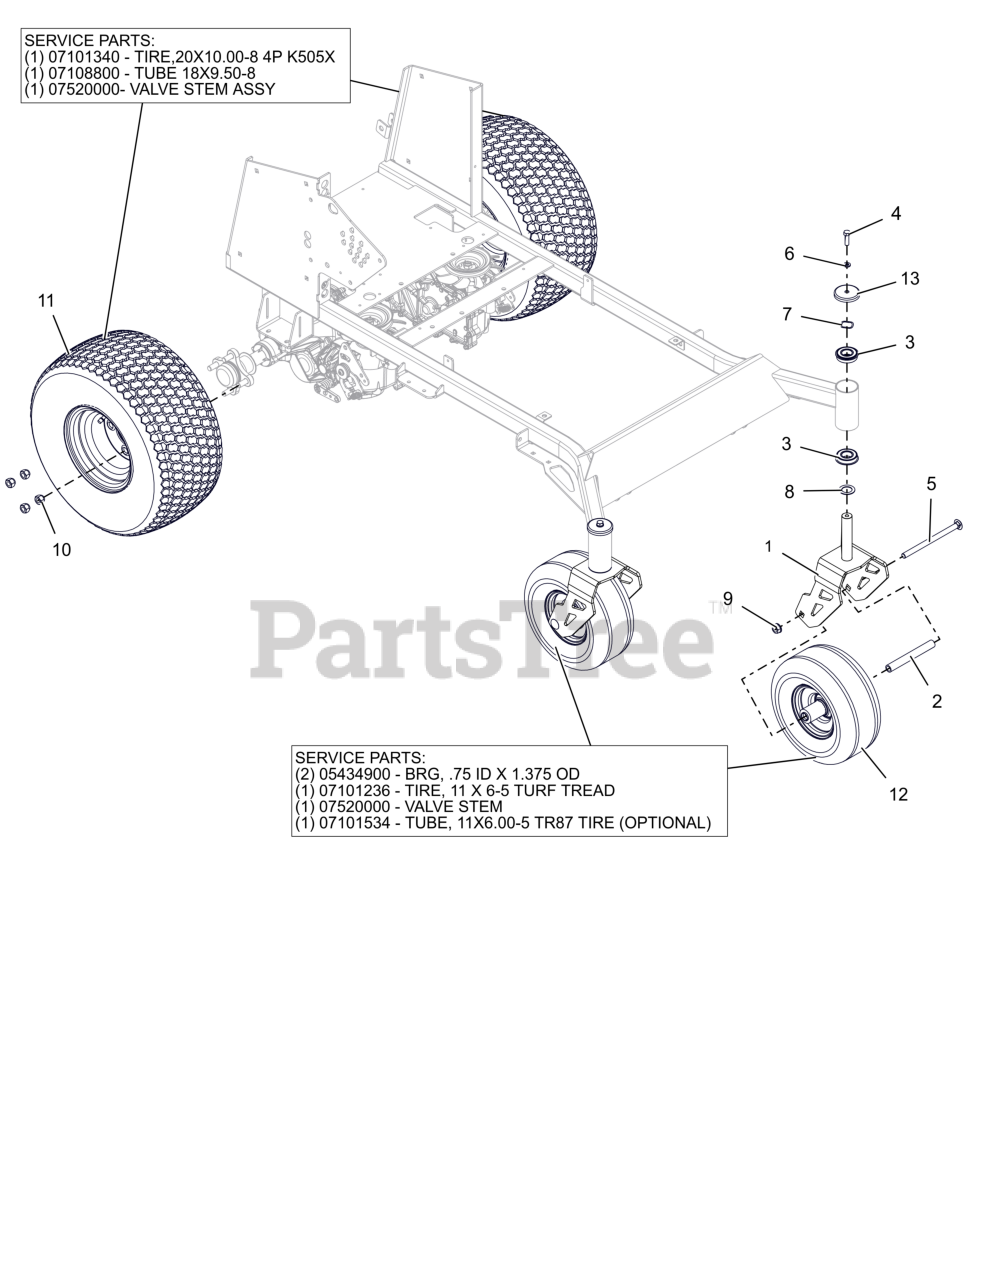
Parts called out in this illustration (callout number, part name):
1	WLDMT- CASTOR FORK
2	SPACER, FRONT WHEEL (WIDE 6.0)
3	BEARING, BALL -2.000 OD X 1.000 ID X .5625 W/RING
4	BLT- HEX .38-16X1.25 G5 ZB500
5	BLT-RHSN .50-13X7.50 G5 ZCC NS
6	WSHR-LK-REG .375X.094 ZB500
7	WSHR-WAVE 1.0X1.25X.028 .145FH
8	WSHR-HRD-THRS 1.007X1.542X.062
9	NUT-LK-CTR-FLG .500-13 GG ZCC
10	NUT, WHEEL .50-20 ZCC
11	ASSM TIRE\WHEEL, 20 X 10 -8
11	LAWN TIRE REAR, 4 PLY kK505 20/10.00-8
11	TIRE TUBE 18/6.50/8.50/9.50-8, 20/8.00/10.00-8 4 PLY TR13 STRAIGHT VALVE
11	VALVE STEM ASS'Y
12	ASM- WHL/TIRE 11 X 6.00-5 BLACK
12	BRG-BALL .752X1.380X.500
12	LAWN TIRE FRONT, 11/6.00-5 SMOOTH
12	VALVE STEM ASS'Y
12	TUBE- 11X6.00-5 TR87 TIRE
13	SHIELD, AXLE BEARING
